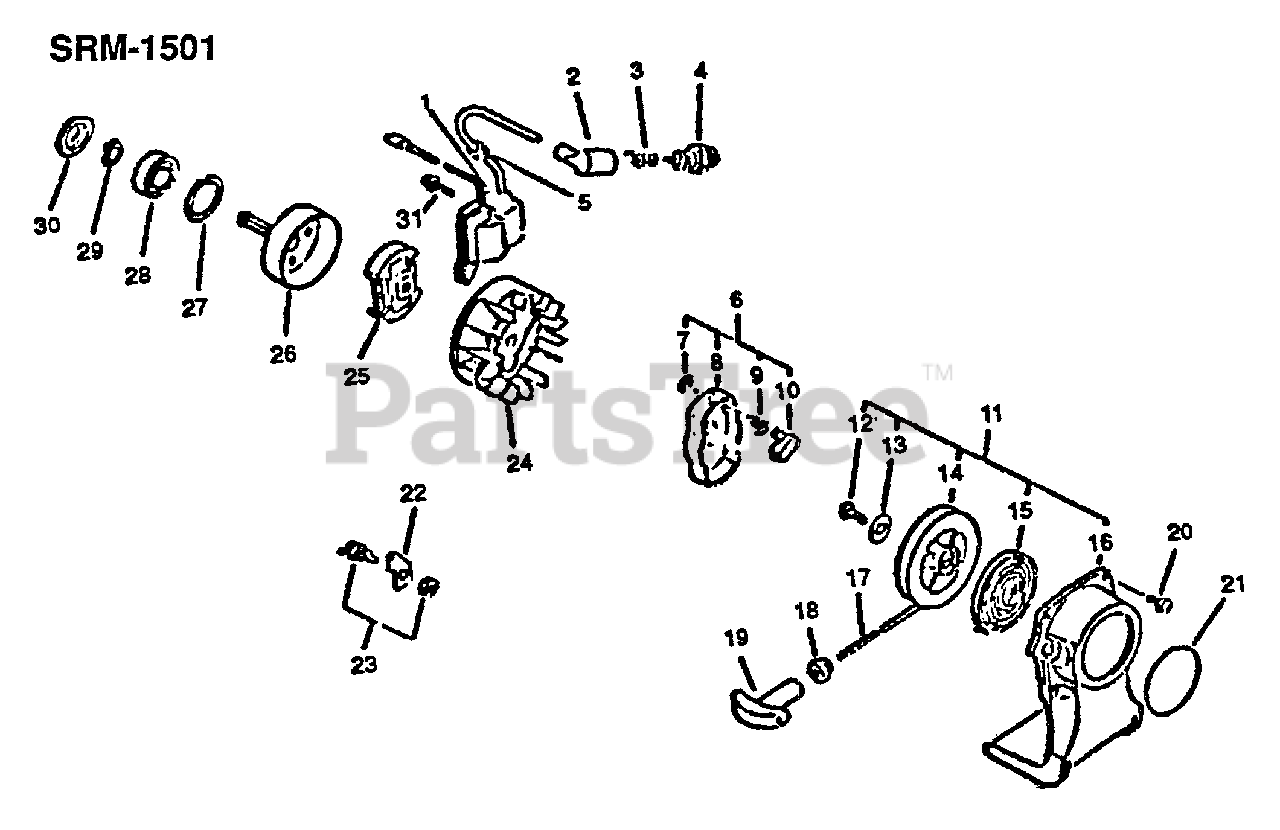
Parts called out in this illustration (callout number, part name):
1	COIL, IGNITION
2	CAP, SPARK PLUG
2	DRUM, CLUTCH
3	TERMINAL, SPARK PLUG
4	SPARK PLUG - BPM7A
6	STARTER PAWL ASSY
7	E-RING 4
8	CATCHER, PAWL
9	SPRING, RETURN
10	PAWL, STARTER
11	STARTER ASSY
13	WASHER
14	REEL, ROPE
15	SPRING, RECOIL
16	CASE, STARTER - BLUE
17	ROPE, STARTER
18	GUIDE, ROPE
19	GRIP, STARTER
20	SCREW 4×16
21	LABEL, ECHO
22	BRACKET, SWITCH
23	SWITCH, ON-OFF
24	FLYWHEEL
25	CLUTCH ASSY
27	RING, SNAP Ø32
28	BEARING, BALL 6001
29	RING, RETAINING - 12
30	STOPPER, PIPE
31	SCREW 4×22
